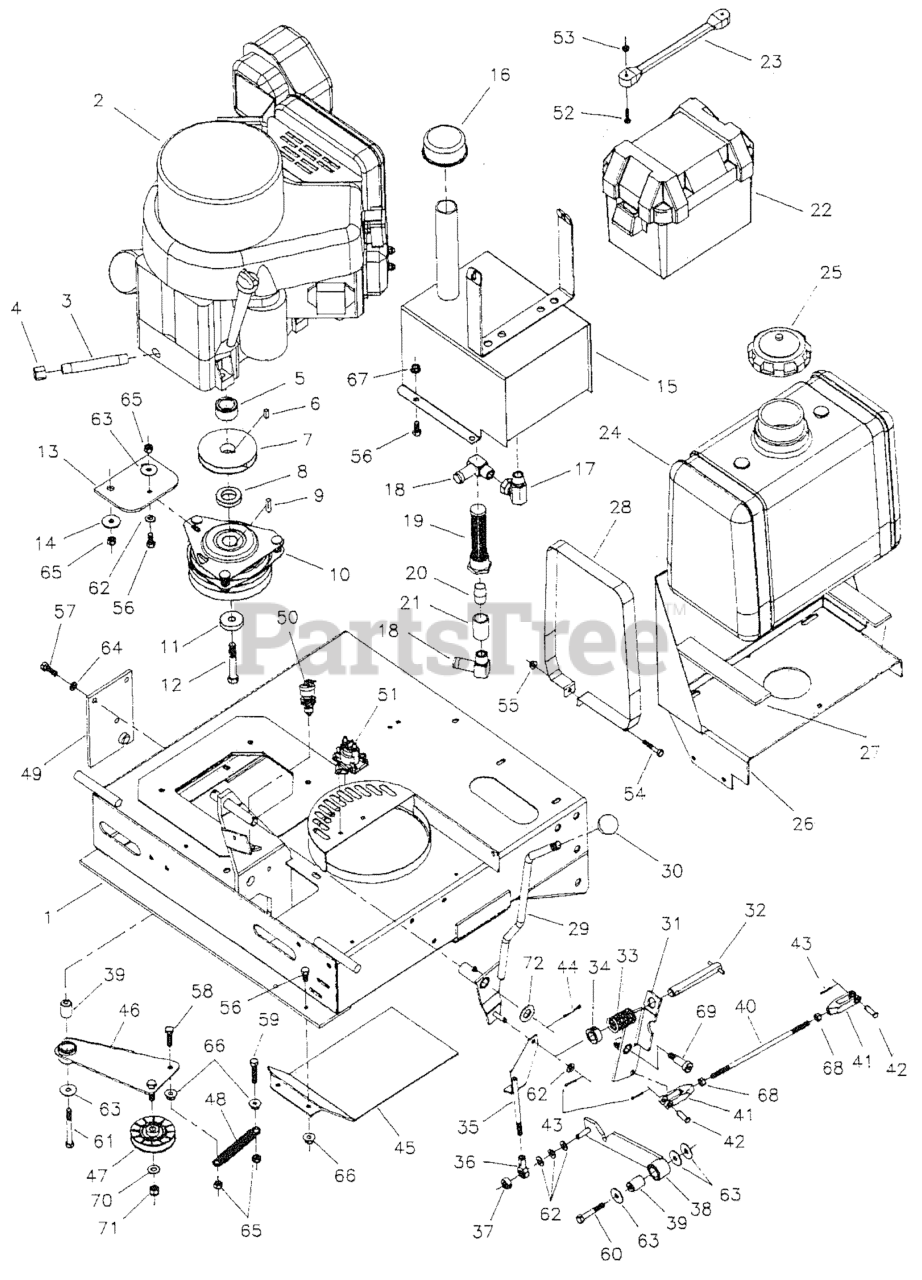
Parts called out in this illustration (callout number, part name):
1	Engine Deck
3	Nipple, 3/8" Nl'T x 4-1/2"
4	Cap, 3/8" NPT
5	Spacer, Crank Shaft
6	KEY, 1/4" SQ. X 1-1/4
7	Pulley, Crank Shaft
8	Spacer, Clutch
9	Key, 1/4" Sq. x 1"
10	Clutch, Electric
11	Washer, Clutch Retaining
12	Bolt, Dri-Lock
13	Pad, Clutch Mount
14	Washer, Clutch Anchor
15	Hydro Tank Assembly (complete wi fittings & breather)
15	HYDRO TANK WELDMENT
16	BREATHER
17	Fitting, 90° 1/2" NPT Swivel
18	Fitting, 90° 112" NPT
19	Strainer, In-Line
20	Nipple, 1/2" NPT Close
21	Coupler, 1/2" NPT
22	Box, Battery
23	Strap, Rubber
24	TANK, FUEL, PLASTIC, 6 GALLON W/ FUEL LINE
25	CAP, FUEL TANK, 3-1/2 NECK
26	Mount, Fuel Tank
27	Pad, Rubber Mount
28	Strap, 6 Gal. Fuel Tank
29	Brake Lever
30	Knob
31	Brake Rocker Arm
32	Bar, Spring
33	Spring, Compression
34	Collar, 5/8" Set
35	Brake Lock
36	BALL JOINT 5/16-24 RH FEMALE BRONZE RACE
37	Collar, 5/16" Set
38	Neutral Lock wi Bushing
38	Bushing, Brass
39	Spacer, Pivot
40	Rod, Brnke Linkage
41	Clevis, 5/16" Plastic
42	Pin, Clevis
43	PIN, 3/32 X 0.750, COT, ZINC/CLEAR
44	PIN, COTTER, 1/8 X 1-1/4
45	Plate, Skid
46	Idler Arm wi Bushing
46	Bushing, Brass
47	Pulley, Idler
48	Spring, Extension
49	WELD, BRACKET, PIVOT - LEFT
49	WELD, BRACKET, PIVOT - RIGHT
50	Switch, Plunger
51	Solenoid, Starter
52	SCREW, #10-24 X 1 RS, CZ
53	Nut, #10-24 Hex Nylon Lock
54	Bolt, 1/4-20 x 1-1/2" GD.5
55	NUT, 1/4-20 HEX SERR. FLANGE
56	BOLT, 5/16-18 X 3/4 GD5
57	Bolt, 5/16-18 xl" GD5
58	BOLT, 5/16-18 X 1-1/4 GD5 TFL, CZ
59	Bolt, 5/16-18 x 1-3/4" TFL GD.5
60	Bolt, 5/16-18 x 2" GD.5
61	Bolt, 5/16-18 x 3" GD.5
62	WASHER, 5/16" SAE
63	Washer, 5/16" Fender
64	WASHER, 5/16 LOCK CZ
65	Nut, 5/16-18 Hex Nylon Lock
66	NUT, 5/16-18 HEX SERRATED FLANGE (LARGE)
67	NUT, 5/16-18 HEX SERRATED FLANGE (SMALL)
68	Nut, 5/16-24 Hex
69	Bolt, 3/8-16 - 112" Dia. x I" Shoulder
70	WASHER, 3/8 SAE
71	NUT, 3/8-16 HEX NYLON LOCK
72	Washer, 5/8" SAE
73	Fuel Line, 25" Long (tank to filter)
74	Filter, Fuel
75	Fuel Line, 19" Long (filter to engine)
76	Clamp, Hose (for fuel line)
77	Wire Loom, 24" Long (covers fuel line #1550831-25)
